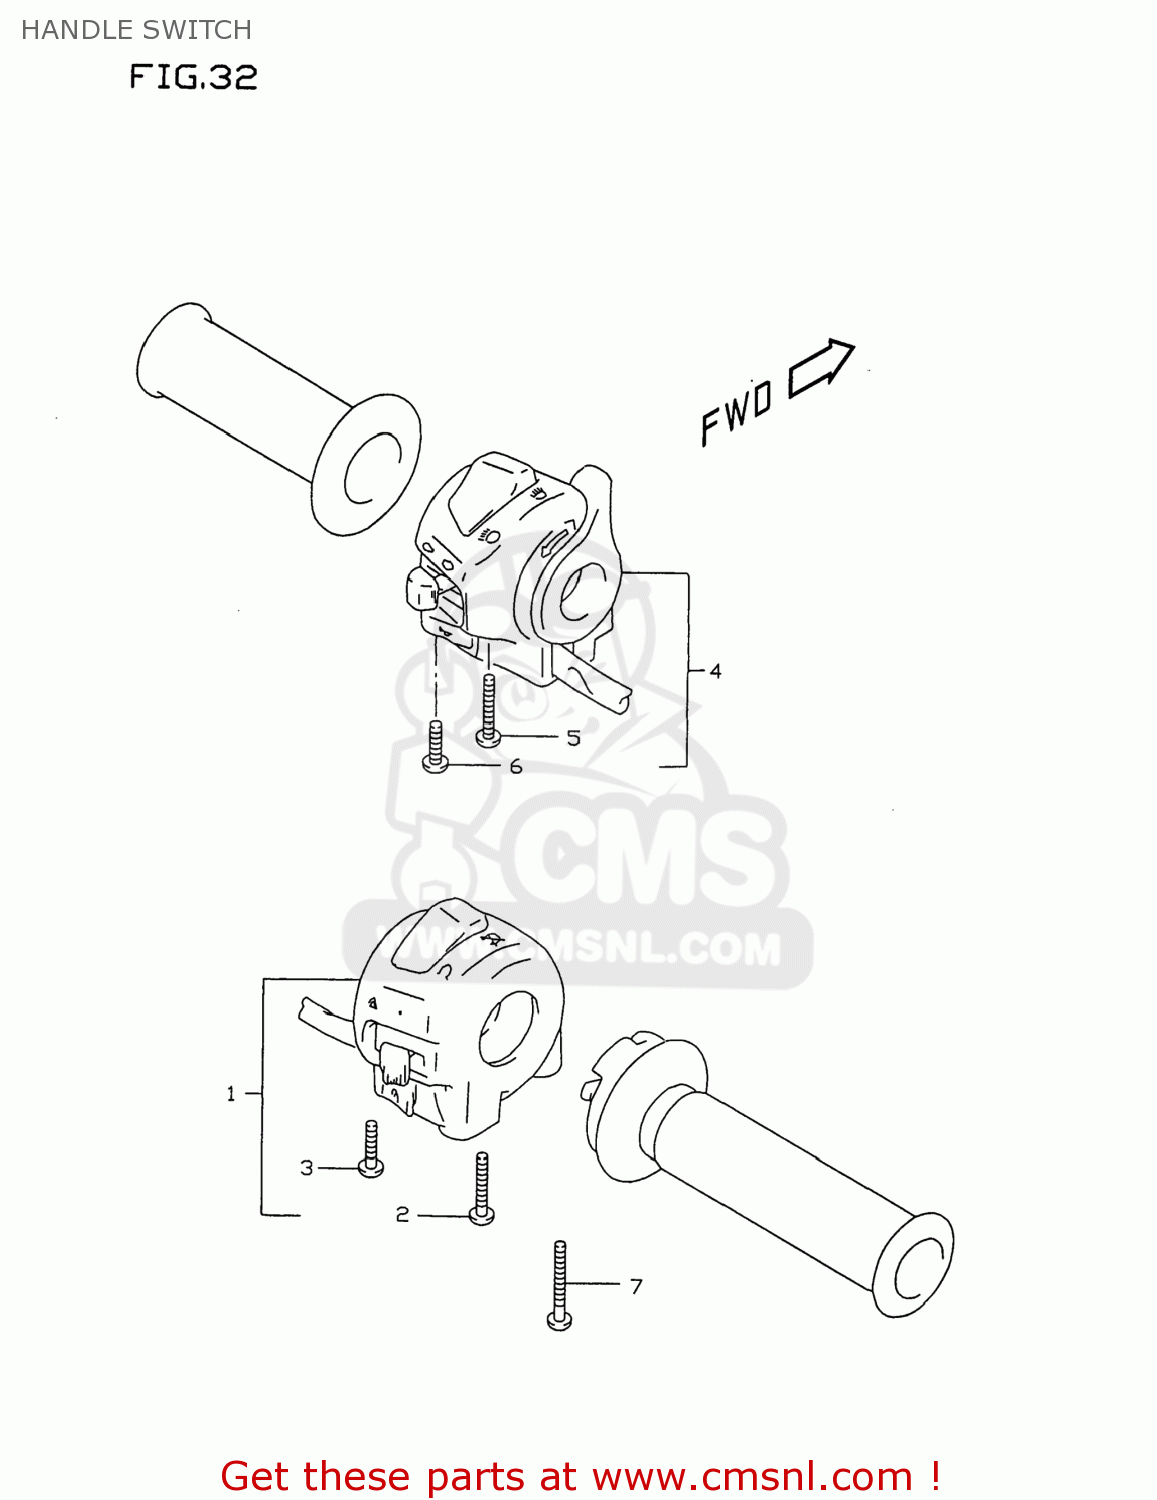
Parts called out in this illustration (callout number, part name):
1	SWITCH ASSY,HANDLE,R
2	SCREW
3	SCREW
4	SWITCH ASSY,HANDLE,L
5	SCREW, 5X45
6	SCREW
7	SCREW
